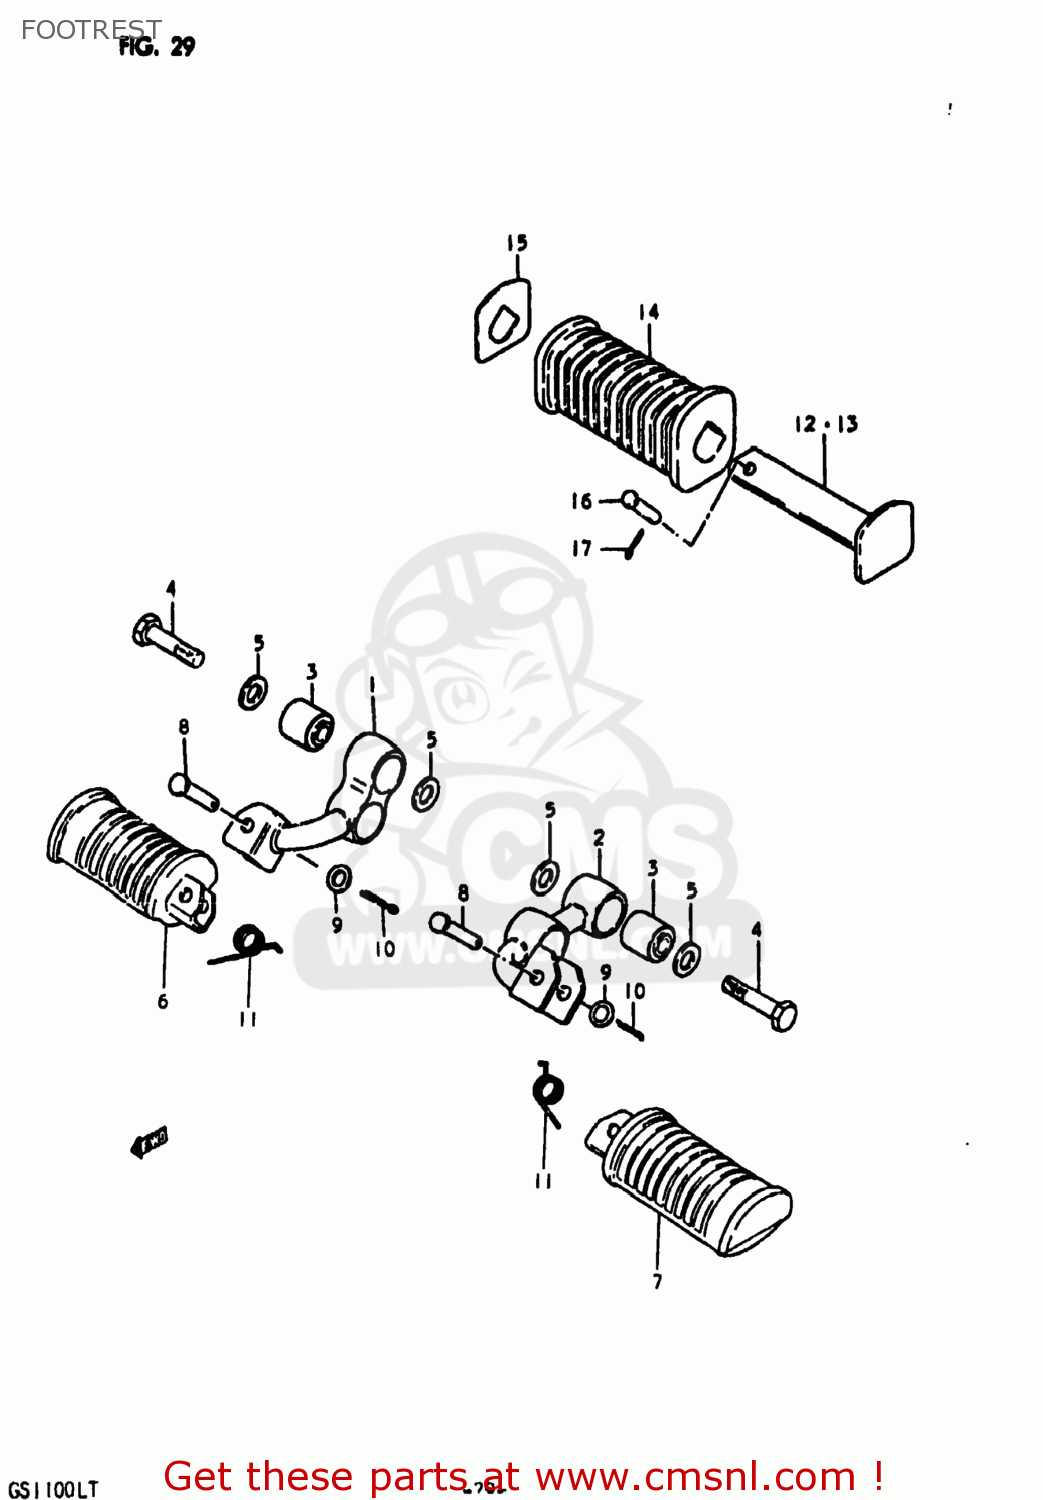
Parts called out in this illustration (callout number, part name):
1	BAR,FRONT FOOTREST,RIGHT
2	BAR,FRONT FOOTREST,LEFT
3	BUSH
4	BOLT
5	WASHER
6	RUBBER,FRONT FOOTREST
7	FOOTREST
8	PIN
9	WASHER
10	PIN
11	SPRING
12	BAR,REAR FOOTREST
13	BAR,REAR FOOTREST
14	RUBBER,REAR FOOTREST
15	WASHER,REAR FOOTREST RUBBER
16	PIN
17	PIN
